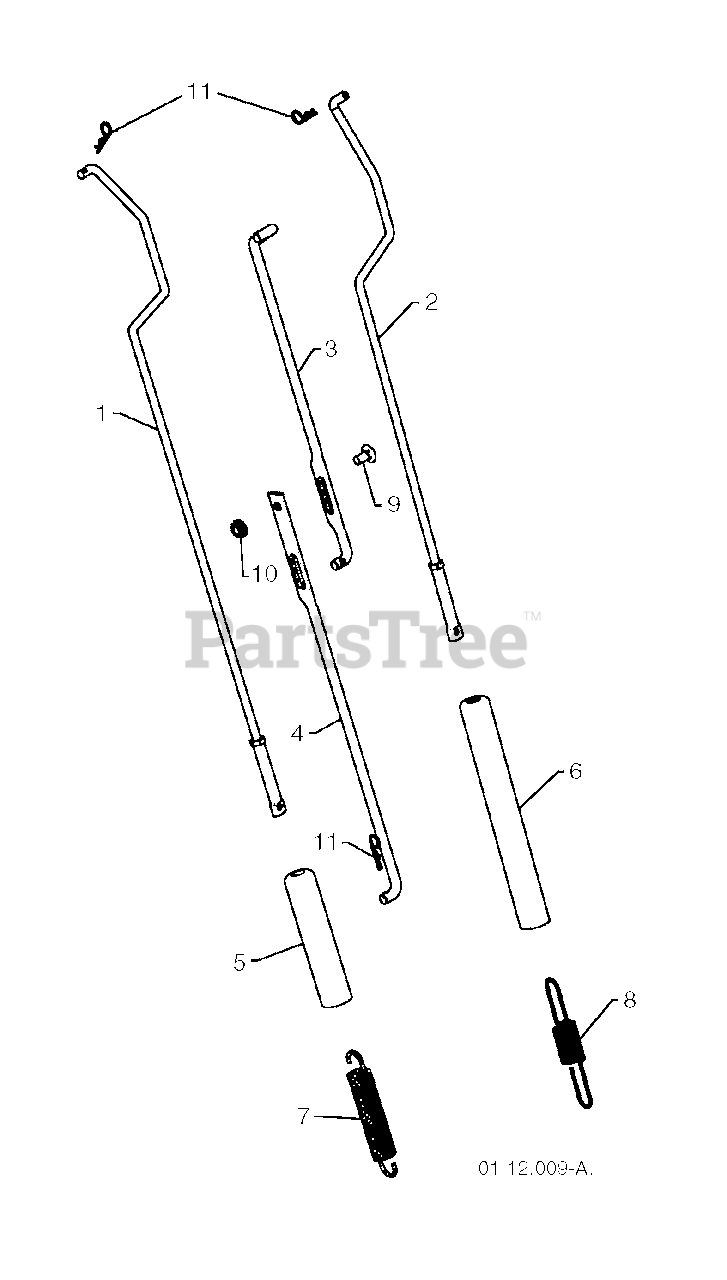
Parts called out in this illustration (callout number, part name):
1	ROD.ASM.IMPELLER.HYD
2	ROD.ASM.TRACTION.HYD.CLUTCH
3	ROD.SHIFTER.TOP.HYD.SNOW
4	ROD, LOWER, SPEED CONTROL
5	SLEEVE, SPRING
6	SLEEVE, SPRING
7	SPRING, AUGER CONTROL
8	SPRING, TRACTION DRIVE
9	BOLT
10	NUT.FLANGE.5/16
11	SPRING RETAINER
